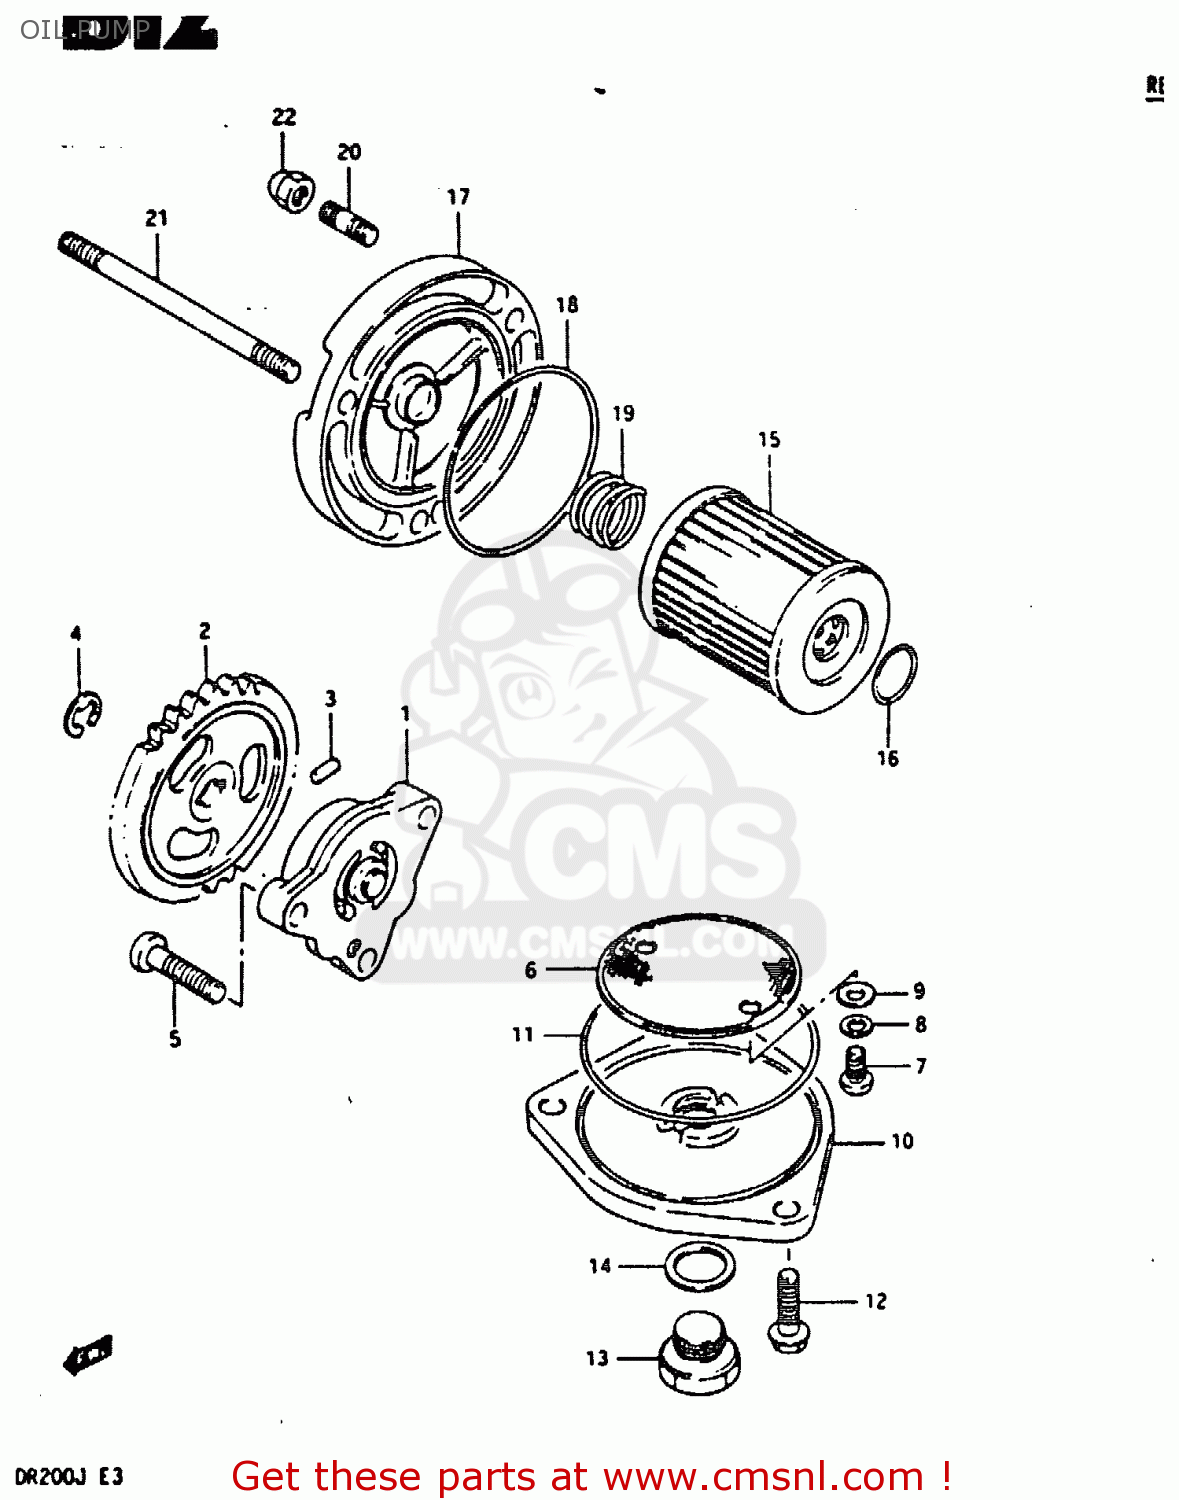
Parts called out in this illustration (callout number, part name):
1	PUMP ASSY,ENGINE OIL
2	GEAR,OIL PUMP DRIVEN (N
3	PIN(2.5X11.8)
4	E RING 6MM
5	SCREW
6	STRAINER,ENGINE OIL
7	SCREW 5X12
8	LOCK WASHER
9	WASHER
10	CAP,OIL STRAINER
11	O RING(D:2.4,ID:60.5)
12	BOLT
13	PLUG
14	GASKET(14X19.2X2) (NAS)
15	FILTER,OIL
16	O RING(D:1.9,ID:13)
17	CAP,OIL FILTER
18	O RING(D:2.4,ID:52.6)
19	SPRING
20	STUD 6X12
21	STUD BOLT
22	NUT 6MM
